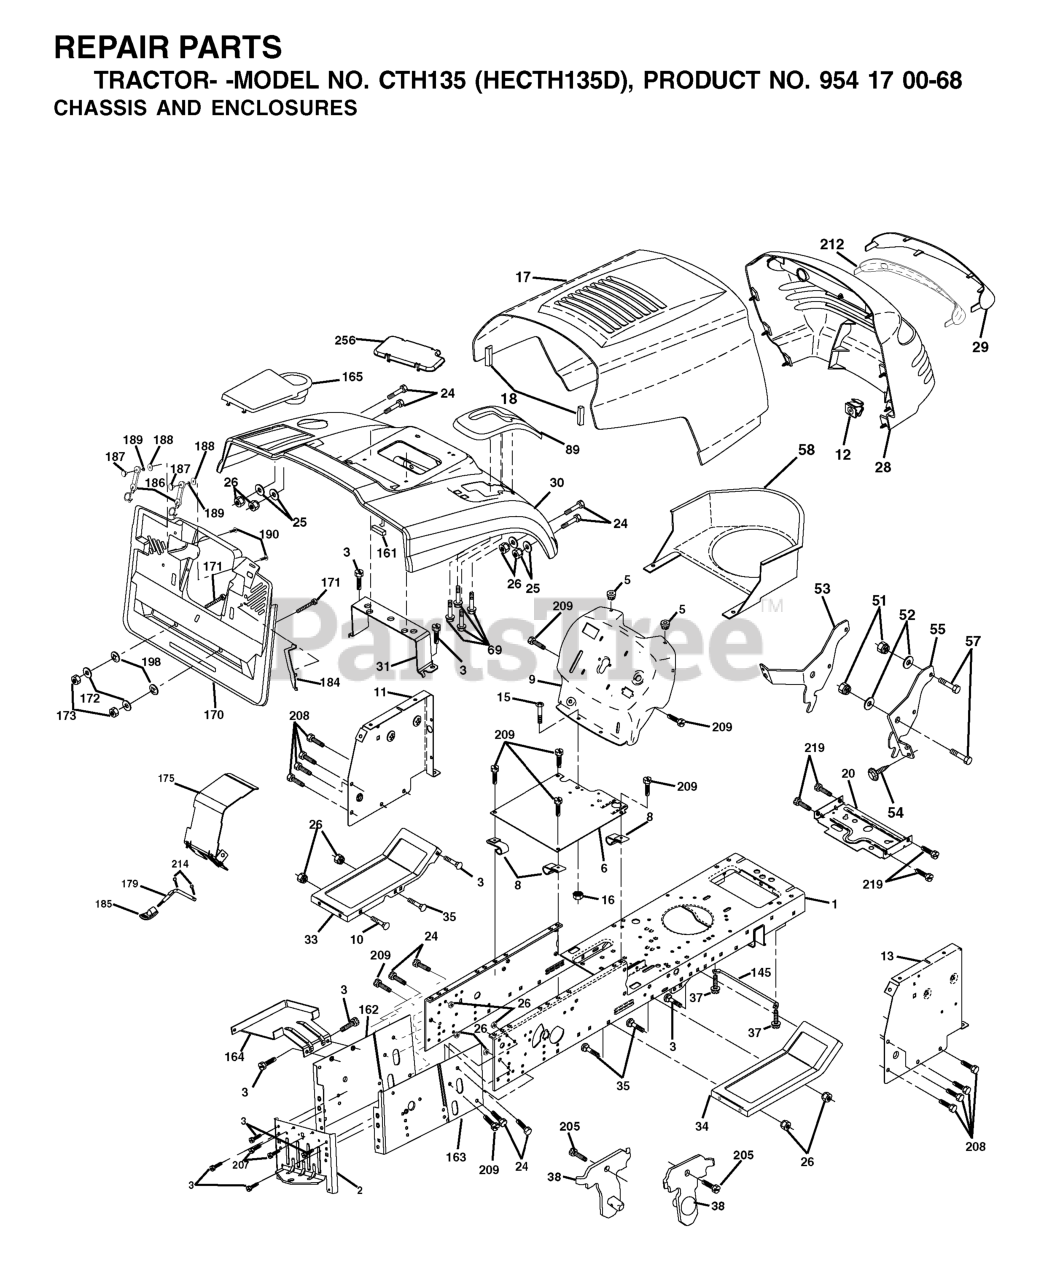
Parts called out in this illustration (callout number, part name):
2	DRAWBAR
3	SCREW 3/8-16X3/4
5	BUMPER.RUBBER.HOOD
6	SADDLE FLAT
8	CLIP,INSULATOR
10	BOLT D
11	PANEL.DASH.LH.LTX
13	PANEL ASM, DASH RH
15	Screw, Machine, Truss Head 5/16-18 UNC x 3/4
16	NUT
17	HOOD ASM.
18	BUMPER HOOD T
20	PLATE MTG.BATTERY/FUEL TANK
25	WASHER
26	NUT
28	GRILLE/LENS ASM
29	LENS
31	BRACKET SUPPORT FENDER
33	FOOTREST PNT LH
34	FOOTREST PNT RH
37	Screw 5/16-18 x 1/2 Hex, Self Tapping 5/16-18 x 1/2
38	BRACKET ASM PIVOT MOWER REAR
51	LOCKNUT.NYLOC.1/4-20
53	BRACKET.GRILLE.LH
54	SCREW.HEX.WS.HD.8-18 X 7/8
57	BOLT
58	AIR DUCT P/L/LT
69	SCREW.HI-LO.CONSOLE
89	COVER.BATTERY.CRD.GREY
145	ROD PIVOT CHASSIS/HOOD
161	EXTRUSION BUMPER (3 2) (2 2)
162	BRACKET
163	BRACKET EXTEN CHASSIS RH CRD
165	RP.COVER.BATTERY.CRD.GREY
172	WASHER
184	BRACKET.ACTUATOR.BAGGER.SRD
186	LATCH ASSY
187	WELDNUT
189	LOCKWASHER #10
190	SCREW
207	SCREW, 5/16-18 X 1/2
208	SCREW 3/8-16X1/2
209	SCREW, 3/8-16X3/4
212	REPL BY 532 1745-03
214	RETAINER M
219	SCREW
256	COVER FENDER CRD
